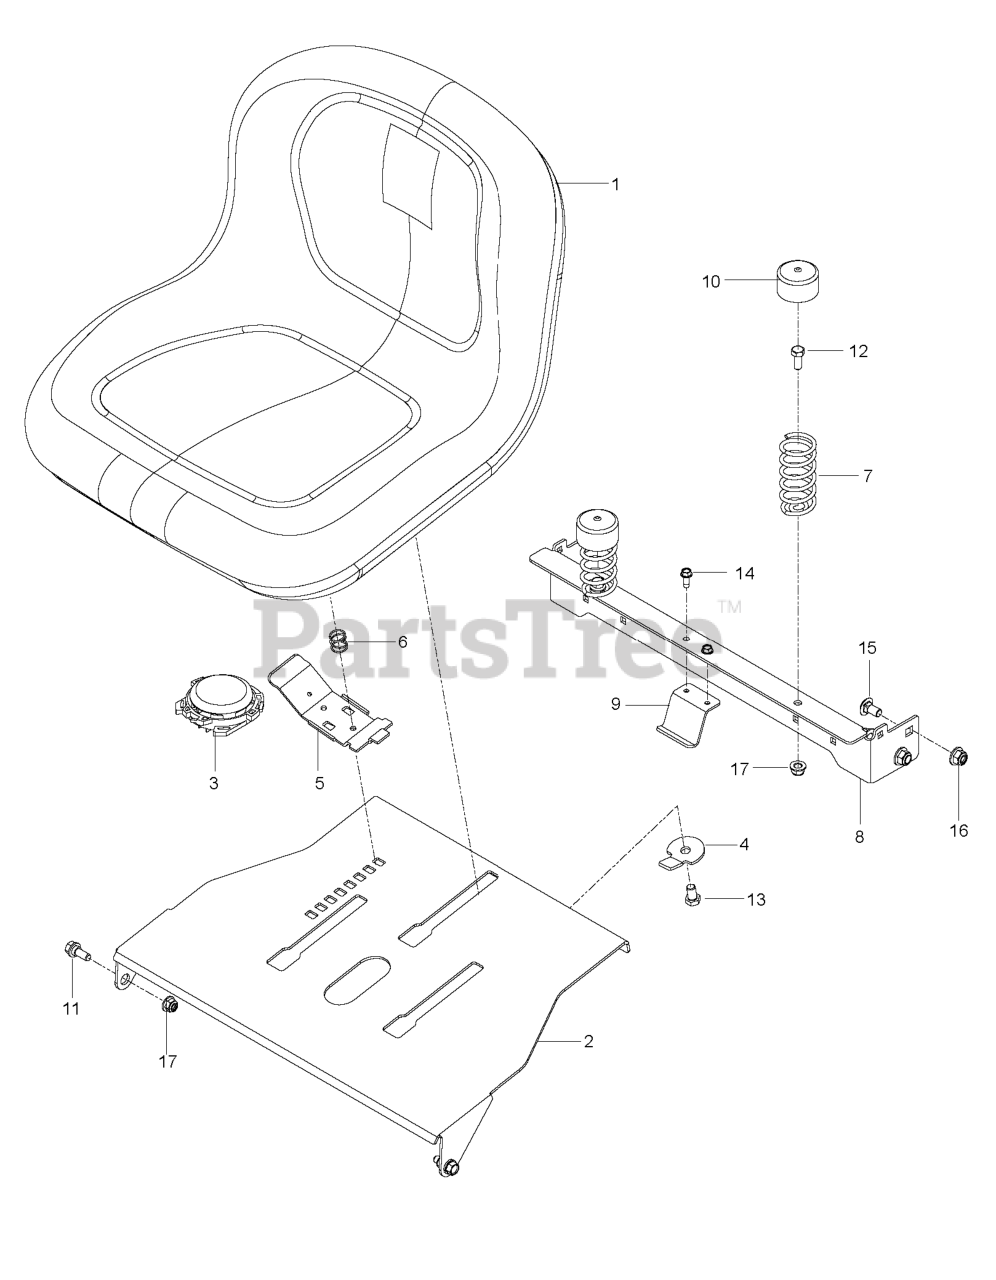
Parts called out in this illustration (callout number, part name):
1	SEAT.TH150.MS498.GRY.HUSQ.TEX
2	PLATE, SEAT, ORG
3	SWITCH, SEAT N/C
4	STOP, SEAT, BLACK
5	HANDLE.SLIDE.SEAT.TEX.BLACK
6	SPRING.LATCH.SEAT.TEX
7	SEAT SPRING
8	SUPPORT, REAR SEAT, ORG
9	HOLDING DEVICE, FUEL TANK, BLK
10	SPRING CAP
11	BOLT, SHOULDER
12	BOLT.FIN.HEX.5/16-18X3/4
13	HCS 3/8-16 X 5/8 GR 5 ZD
14	SCREW 1/4 X 5/8
15	Bolt - Rd. Hd. Sq. Neckiage 3/8 16 x 3/4
16	5/16-18 NYLOC FLANGE NUT
17	NUT 3/8-16 HEX FLG NYLOC ZD
